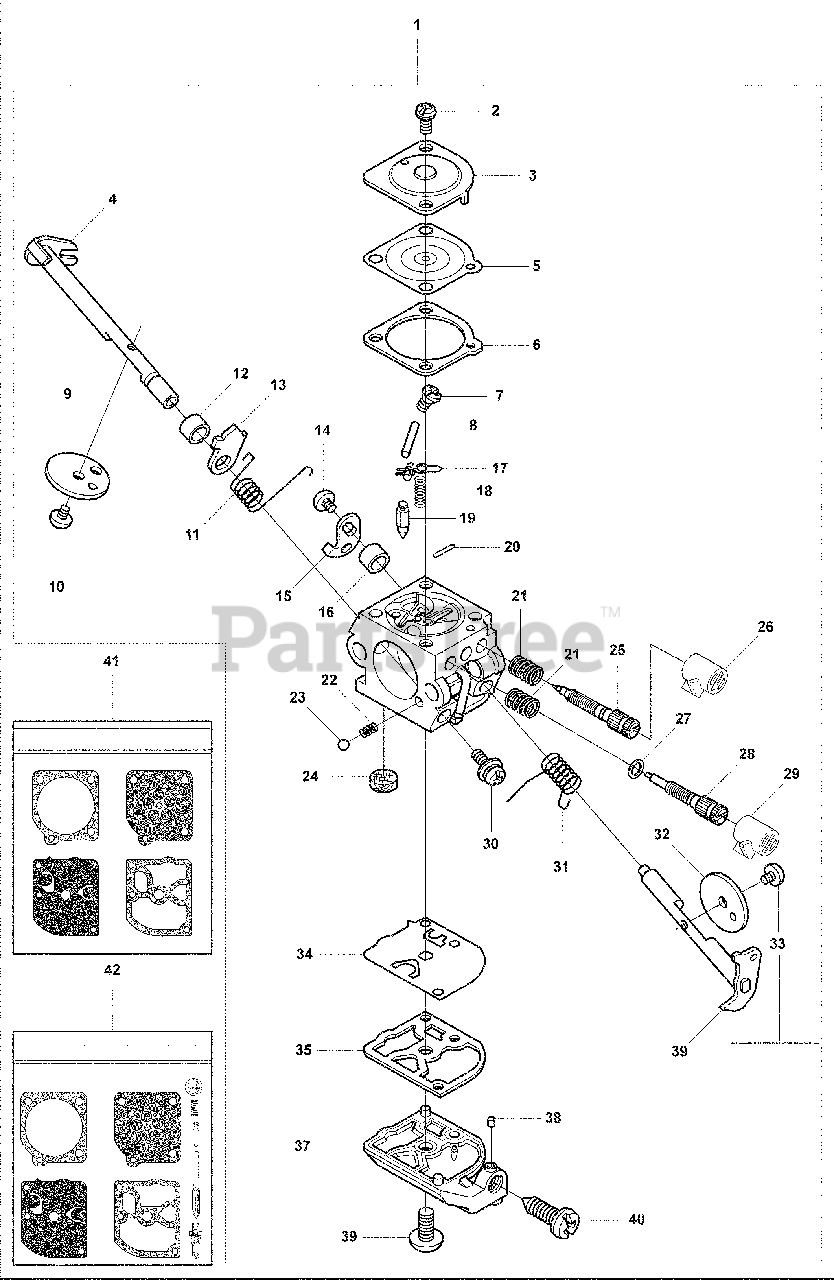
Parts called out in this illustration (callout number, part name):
1	Carburetor Kit
8	Pin
18	Spring
19	Inlet Needle
21	Spring
25	LOW SPEED NEEDLE
28	NEEDLE HIGH SPEED
31	Throttle Spring
32	THROTTLE FLAP
34	Pump Diaphragm
41	Gasket Kit, Zama GND39
42	Carburetor Repair Kit, Zama RB69
